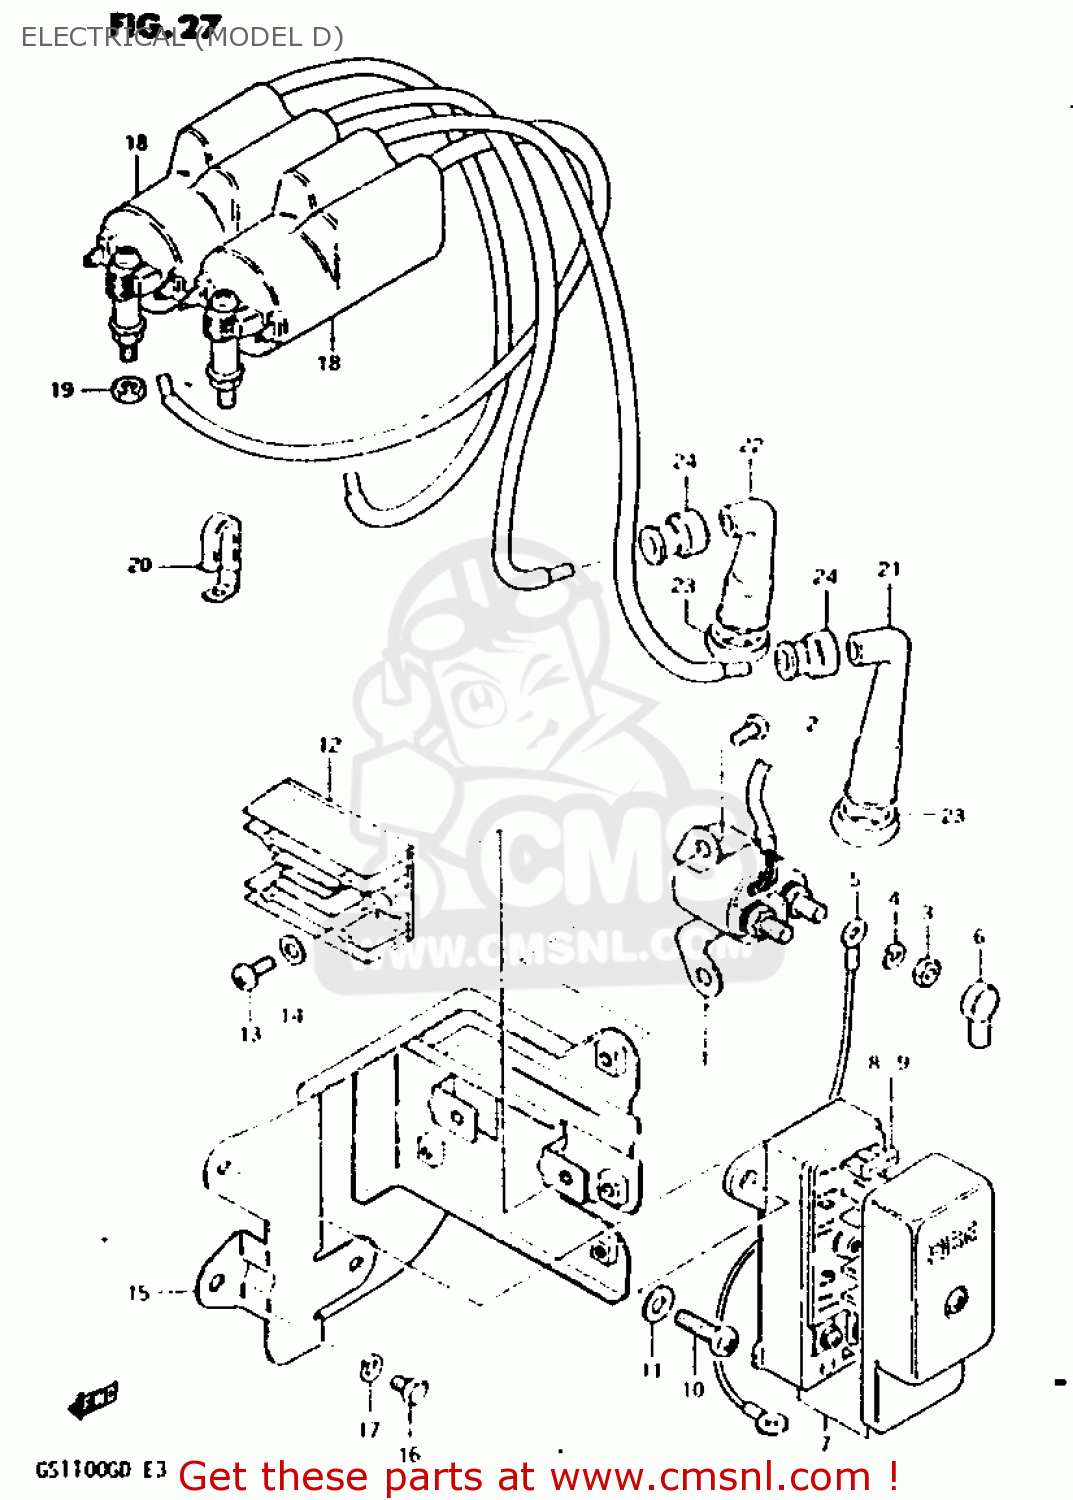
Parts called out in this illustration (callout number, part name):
1	RELAY ASSY,STARTING MOTOR
2	SCREW(6X10)
3	NUT 6MM
4	WASHER,LOCK
5	CABLE,STARTING MOTOR
6	CAP,TERMINAL
7	BOX ASSEMBLY,FUSE
8	FUSE(10A)
9	FUSE(15A)
10	SCREW 6X12
11	WASHER
12	RECTIFIER ASSEMBLY
13	SCREW
14	WASHER
15	HOLDER COMP,ELECTRONIC PARTS
16	BOLT
17	WASHER,LOCK
18	COIL ASSEMBLY,IGNITION
19	NUT
20	CLAMP
21	CAP ASSY,SPARK PLUG
22	CAP,SPARK PLUG
23	SEAL,SPARK PLUG
24	SEAL,SPARK PLU
